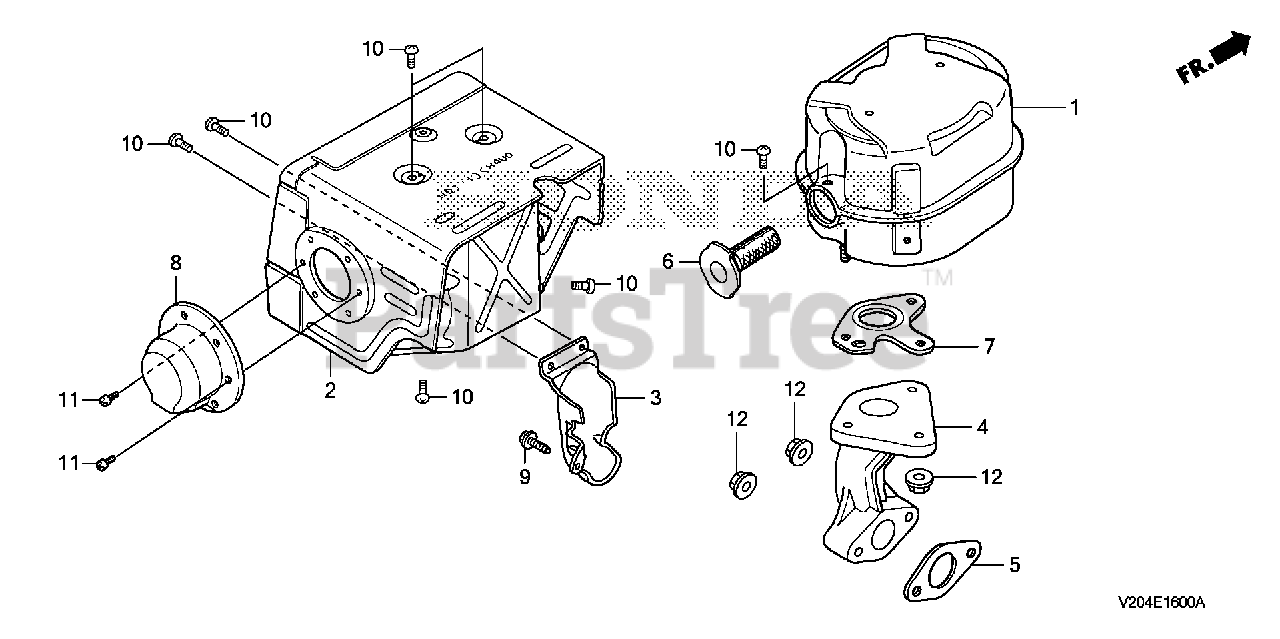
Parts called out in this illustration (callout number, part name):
2	PROTECTOR, MUFFLER (STD)
3	PROTECTOR, EX. PIPE
5	GASKET, EX. PIPE Use up to Engine SN 2949254.
5	GASKET, EX. PIPE (WACKER)
6	ARRESTER, SPARK
7	GASKET, MUFFLER (ARRESTER)
8	DEFLECTOR, MUFFLER
9	BOLT, FLANGE (6X12) (CT200)
10	SCREW, TAPPING (5X8)
11	SCREW, TAPPING (4X6)
12	NUT, FLANGE (8MM)
